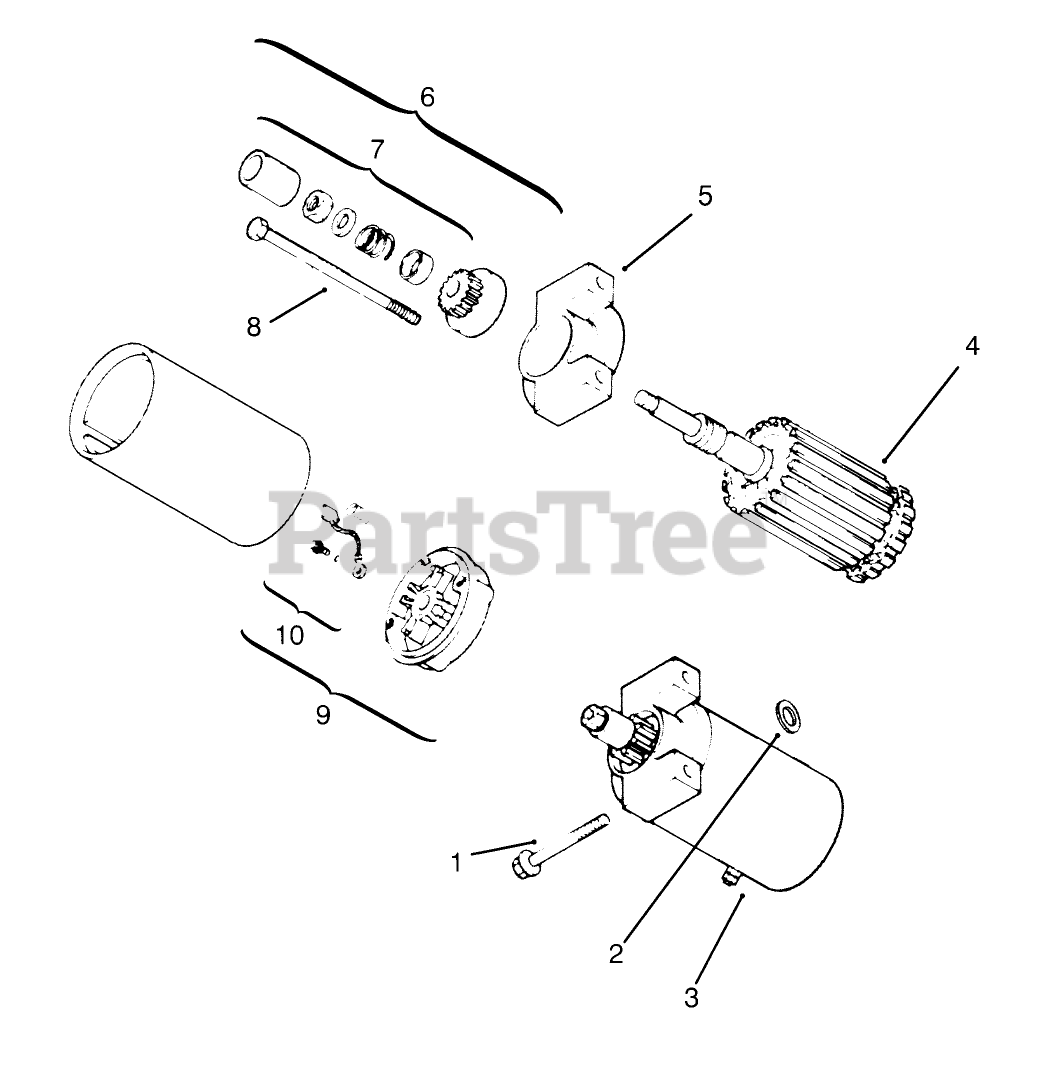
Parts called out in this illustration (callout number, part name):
1	Screw M8x1.25x70 (Only On: 72042,72043,72062,72063)
2	Washer (Only On: 72042,72043,72062,72063)
3	Starter ASM INCL 4- 10 (Only On: 72042,72043,72062,72063)
4	Armature (Only On: 72042,72043,72062,72063)
5	Cap-Drive End (Only On: 72042,72043,72062,72063)
6	Kit-Drive INCL 7 (Only On: 72042,72043,72062,72063)
7	Kit-Drive Parts (Only On: 72042,72043,72062,72063)
8	Screw-HF (Only On: 72042,72043,72062,72063)
9	Cap-Commutator INCL 10 (Only On: 72042,72043,72062,72063)
10	Kit-Brush And Spring (Only On: 72042,72043,72062,72063)
